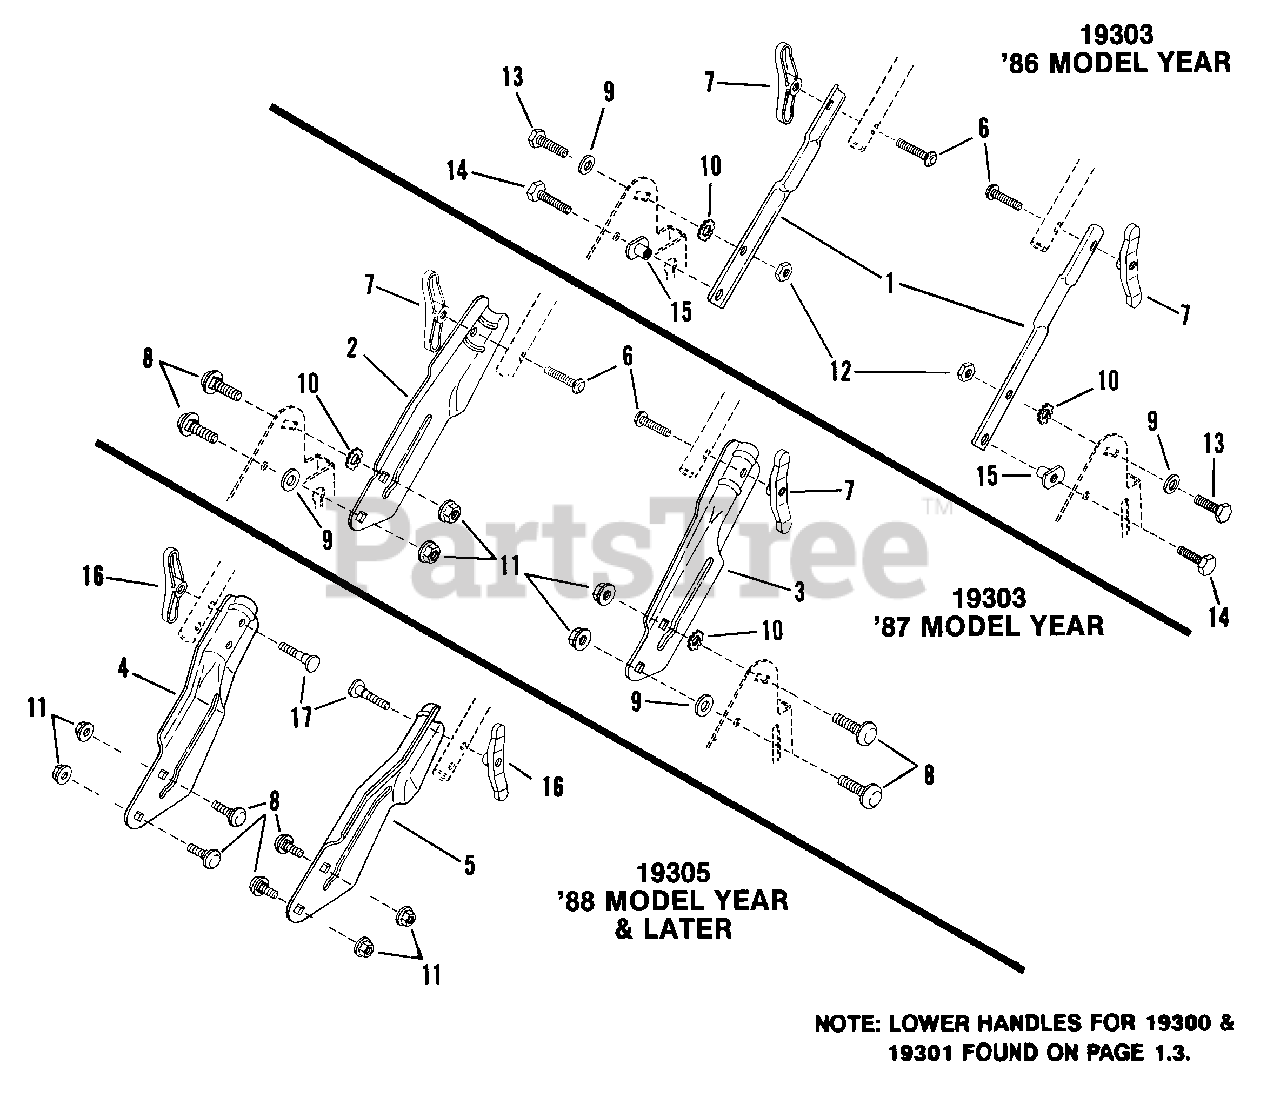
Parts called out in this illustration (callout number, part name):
1	HANDLE, Lower
2	HANDLE, Lower R.H.
3	HANDLE, Lower L.H.
4	HANDLE, Lower R.H.
5	HANDLE, Lower L.H.
6	BOLT, 1/4-20 x 1-3/4" Short Neck Carriage
7	NUT, 1/4-20 Wing
8	BOLT, 5/16-18 x 5/8" Short Neck Carriage, Grade 5
9	WASHER, 5/16" Flat
10	WASHER, 5/16" Internal/External Tooth Lock
11	NUT, 5/16-18 Hex Flange Lock
12	NUT, 5/16-24 Hex Center Lock
13	SCREW, 5/16-24 x 3/4" Hex Head Cap, Grade 5
14	SCREW, 5/16-15 x 1/2" Hex Head Cap, Grade 2
15	T-NUT, 5/16-18
16	NUT, 1/4-20 Wing
17	SCREW, 1/4-20 x 1-3/8" Curved Head
